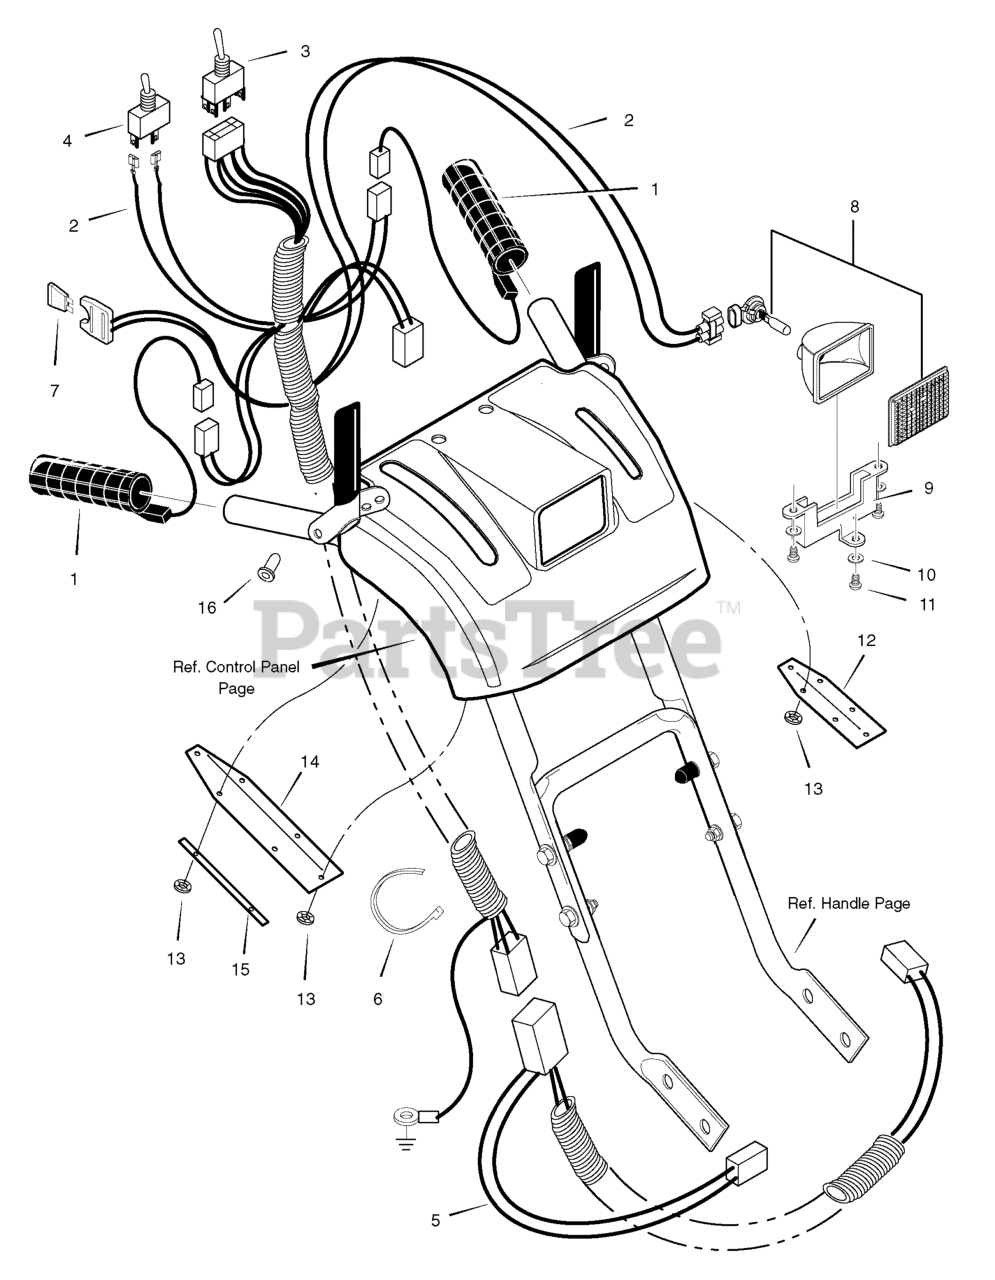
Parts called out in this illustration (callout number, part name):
1	GRIP, HEATED
2	WIRE HARNESS, UPPER
3	SWITCH, CHUTE ROTATION
4	SWITCH, HEATED GRIP
5	WIRE HARNESS, LOWER
6	TIE, CABLE
7	FUSE, 7.5 AMP AUTOMOTIVE
8	HEADLIGHT ASSEMBLY *
9	BRACKET
10	WASHER, FLAT
11	SCREW #8 X 0.50
13	NUT, PUSH
16	RIVET, 0.125 X 0.23
